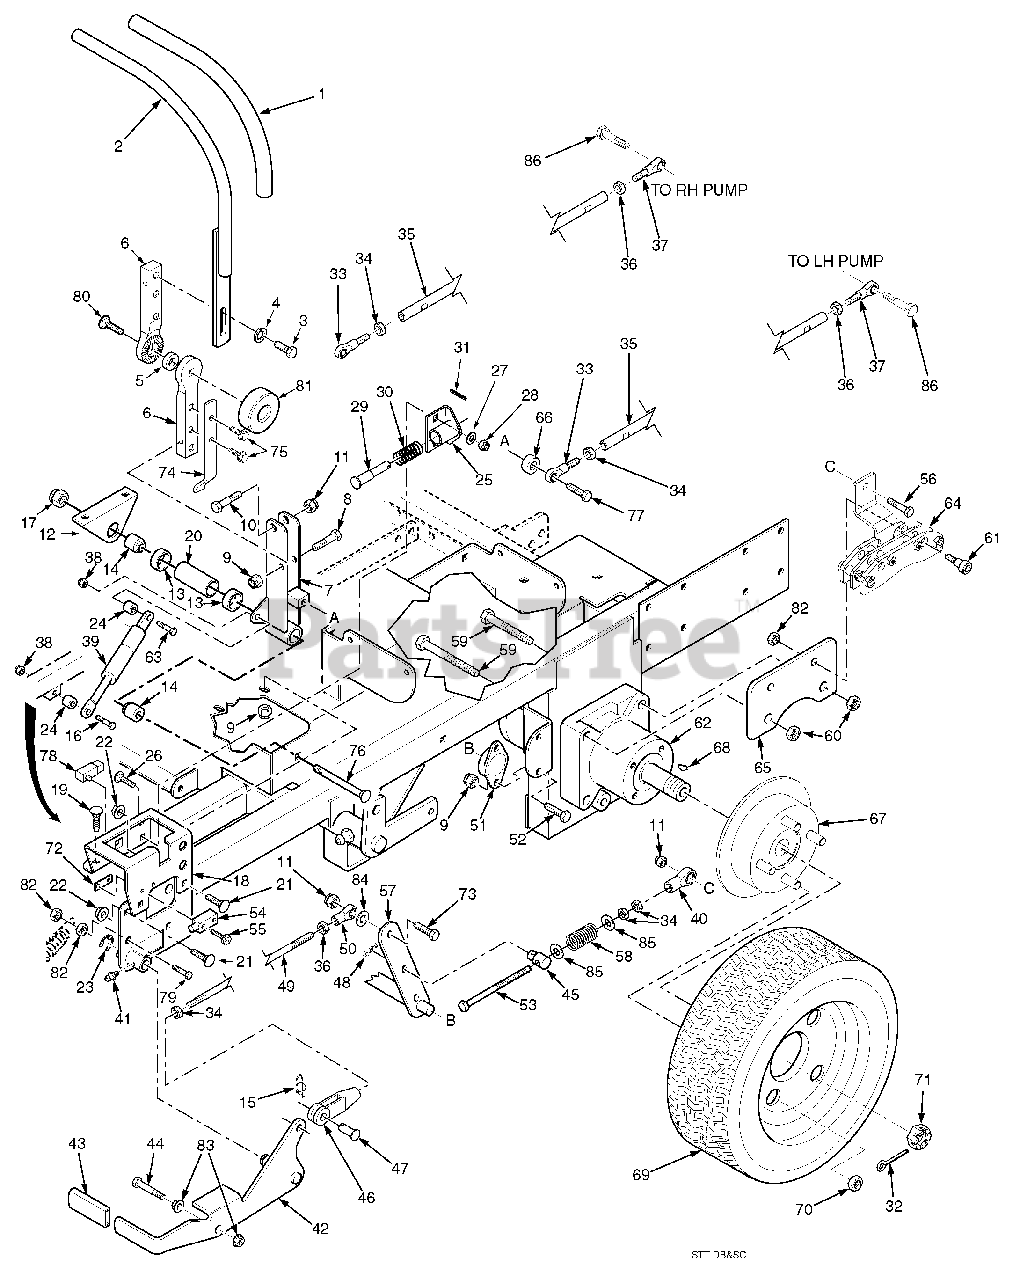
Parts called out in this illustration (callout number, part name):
1	Grip, Handle Bar
2	Handle Bar, LH
3	Bolt, Hex Head 5/16-18 x 1"
4	Lockwasher, 5/16"
5	Rubber Spacer
6	Bar, Control Lever
7	Control Lever Weldment, LH
8	Bolt, Hex Head 5/16-18 x 2"
9	Nut, Hex Elastic Stop 5/16-18
10	Bolt, Hex Head 3/8-16 x 2"
11	Nut, Hex Elastic Stop 3/8-16
12	Mount, Control Linkage
13	Ball Bearings, Neutral Return
14	Spacer
15	Pin, Rue Cotter 3/8 Dia.
16	Bolt, Hex Head, 5/16-18 x 2.75 Zinc
17	Nut, Hex Elastic Stop 5/8-11
18	Bracket, Control Lever LH
19	Bolt, Carriage 5/16-18 x 1"
20	Spacer, Bearing
21	Bolt, Carriage 5/16-18 x 3/4"
22	Nut, Hex Serrated Flange 5/16-18
23	Ring, Retaining 5/8" External "E"
24	Spacer
25	Bracket, Neutral Return
26	Bolt, Carriage 1/4-20 x 3/4"
27	Flatwasher, 1/4" (.312 x .750 x .065)
28	Nut, Hex Elastic Stop 1/4-20
29	Pin, Retaining Spring
30	Spring
31	Roll Pin, Spring 5/32 x 3/4"
32	Pin, Cotter 9/16 x 1-1/2"
33	Rod End, Male 3/8-24 RH Thread
34	Nut, 3/8-24 RH Thread
35	Tube, Control Link
36	Nut, Hex 3/8-24 LH Thread
37	Rod End, Male 3/8-24 LH Thread
38	Locknut, 5/16-18, Elastic Stop
39	Gas Damper
40	Rod End, 3/8-24 RH Female
41	Grease Fitting
42	Lever, Parking Brake
43	Grip, Parking Brake
44	Bolt, Hex Head 3/8-16 x 2-3/4"
45	Swivel Joint
46	Clevis, Traction Control
47	Pin, Clevis
48	Hair Pin Cotter
49	Rod, Parking Brake
50	Rod End, LH Thread
51	Bushing, Self Align
52	Bolt, Hex Head 5/16-18 x 3/4"
53	Bolt, Hex Hd 3/8-24 x 5-1/2"
54	Switch, Parking Brake
55	Screw, Hex Slotted Washer Head #10 32 x 3/4"
56	Bolt, Hex Head 3/8-16 x 1-1/4"
57	Bellcrank, Brake Actuator
58	Spring
59	Bolt, Hex Hd 1/2-13 x 2-3/4" (upper)
60	Locknut, Hex 1/2-13 Center Lock
61	Bolt, Shoulder 1/2 x 3/8-16 x 2-3/4"
62	Wheel Motor, Parker
63	Bolt, Hex Head, 5/16-18 x 1.75, Zinc
64	Brake Caliper
65	Mounting Bracket, Brake
66	Spacer
67	Wheel Hub/Disk Brake Assembly
68	Key, Woodruff 5/16 x 1"
69	Wheel Assembly 24 x 12-12 Turf Master
70	Lug Nut, 1/2-20
71	Nut, Hex Castle
72	Threaded Plate
73	Bolt, Hex Head 3/8-16 x 1-1/2"
74	Actuator, Switch
75	Bolt, Hex Serrtd Flng 5/16-18 x 3/4"
76	Bolt, Hex Head 5/8-11 x 4-1/2"
77	Bolt, Hex Head 3/8-16 x 1-1/4"
78	Switch, Handle Neutral
79	Bolt, Hex Head 3/8-16 x 1-1/4" Grd 8
80	Bolt, Carriage 3/8-16 x 1-1/2"
82	Nut, Center Lock 3/8-16
83	Nut, Serrated Flange 3/8-16
84	Flatwasher, 3/8-.391 x .938 x .105
85	Flatwasher, 3/8-.406 x .812 x .065
86	Bolt, Hex Head, 3/8-16 x 1-3/4"
